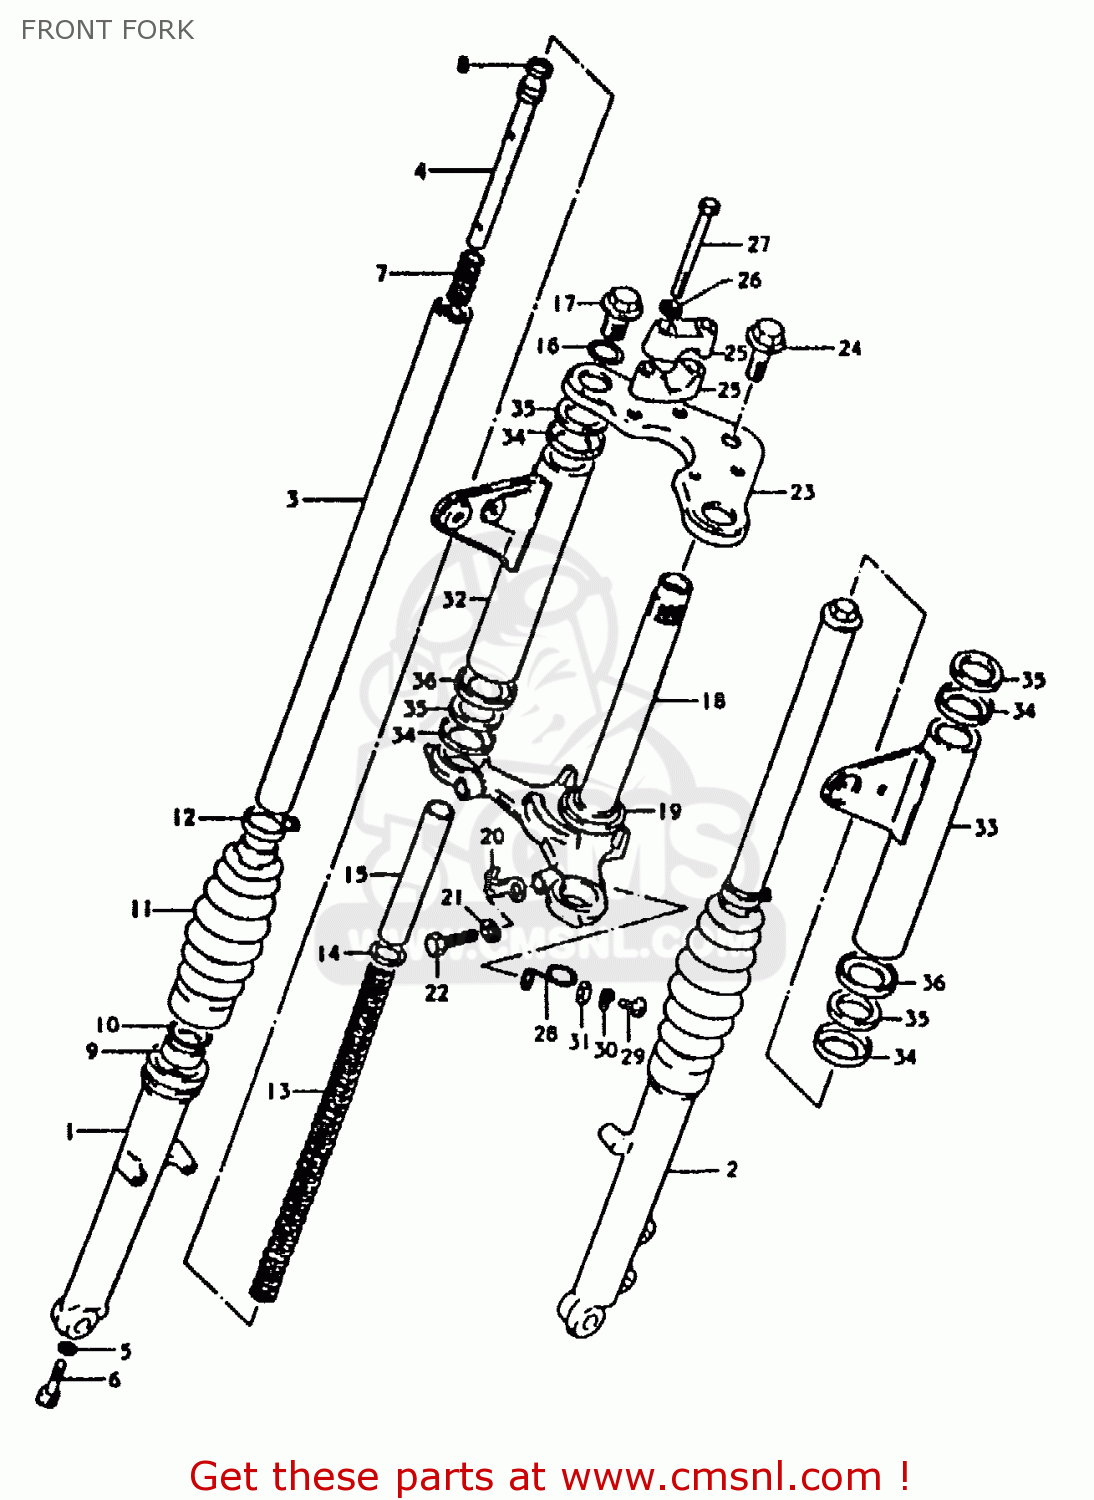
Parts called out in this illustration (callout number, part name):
1	OUTER TUBE, RH
2	OUTER TUBE, LH
3	TUBE,INNER
4	CYLINDER,FRONT FORK
5	GASKET (NAS)
6	BOLT(8X27)
7	SPRING,REBOUND
8	RING,PISTON
9	OIL SEAL,FRONT FORK
10	CIRCLIP,FORK OIL SEAL
11	BOOT
12	BAND
13	SPRING,FRONT FORK
14	JOINT,SPRING
15	SPACER,SPRING
16	O-RING,FORK INNER TUBE
17	CAP
18	STEERING STEM
19	RACE,STEERING OUTER LWR
20	CLIP,CABLE
21	LOCK WASHER
22	BOLT 10X30
23	HEAD,STEERING STEM
24	BOLT
25	HOLDER,HANDLE UPR
26	LOCK WASHER
27	BOLT 8X55
28	CLIP
29	SCREW 6X12
30	LOCK WASHER
31	WASHER
32	BRACKET, HEADLAMP RH
33	BRACKET, HEADLAMP LH
34	SEAT, CUSHION
35	CUSHION
36	SEAT, HEADLAMP BRACKET
